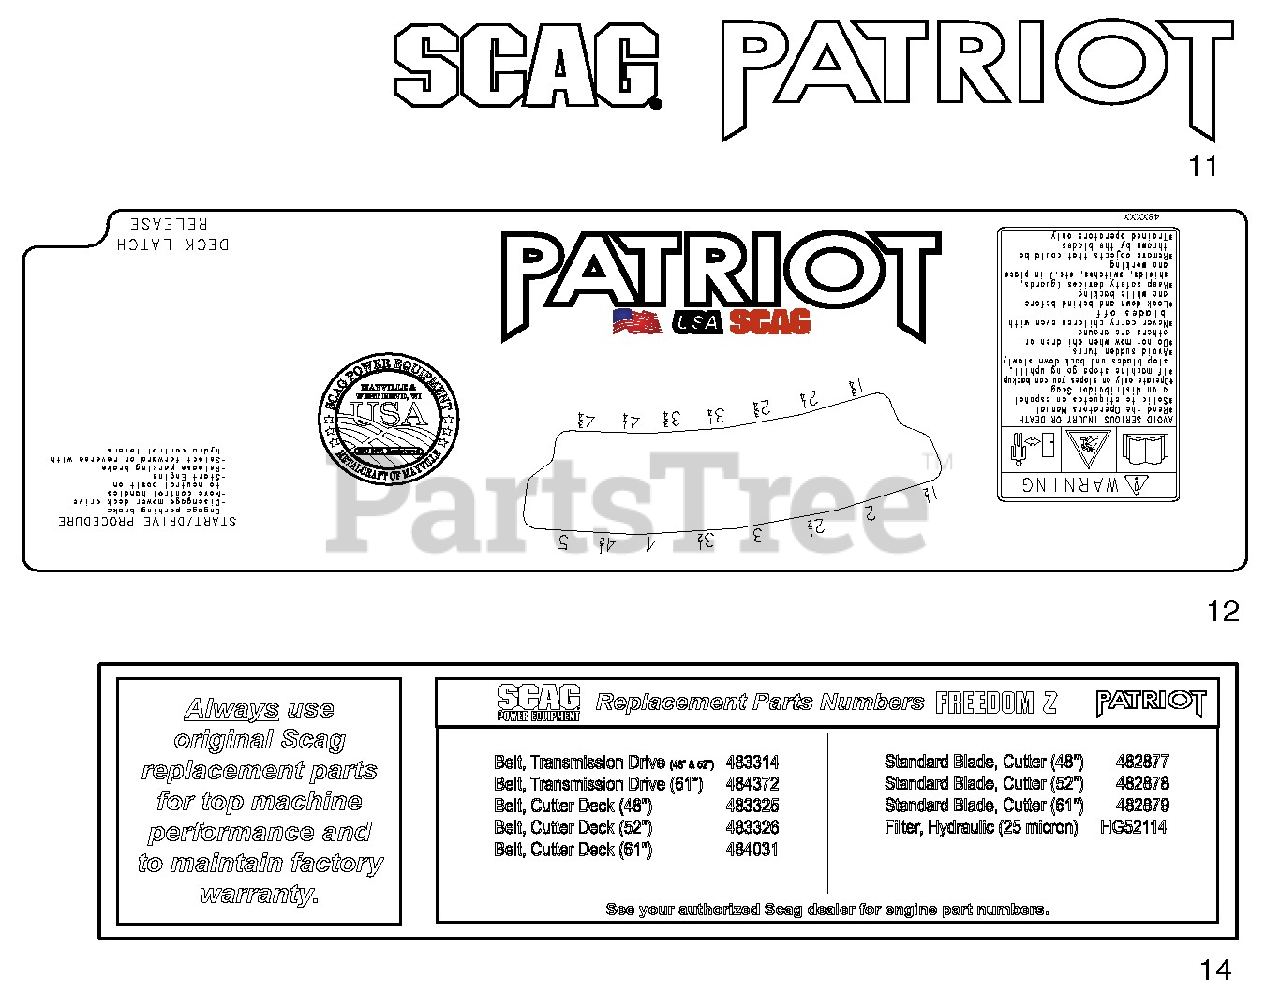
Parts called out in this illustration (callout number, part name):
11	Decal, Front SPZ
12	Decal, Cutting Height - SPZ
14	Decal, SFZ / SPZ Replacement Parts
15	Decal, SZL / SFZ / SPZ Belt Routing
